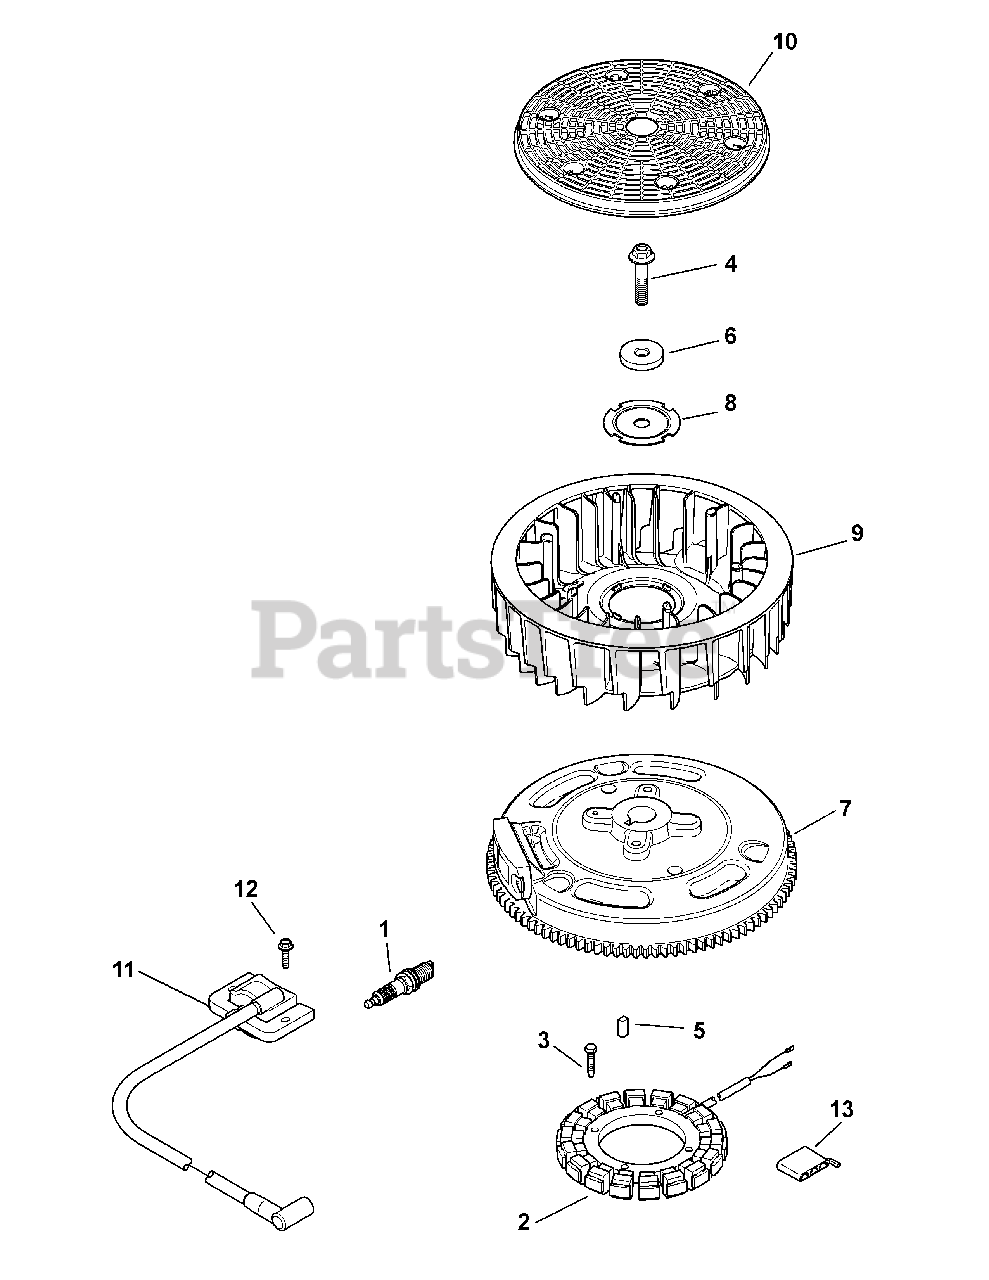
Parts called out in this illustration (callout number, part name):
1	Spark Plug
2	15 Amp Stator Kit
3	Screw, M5 x 0.8 x 25
4	Hex Flange Screw
7	Flywheel Assembly
8	Fan Mounting Plate
9	Fan
11	Module Ignition Kit
12	Flange Screw, M5 x .8 x 20
